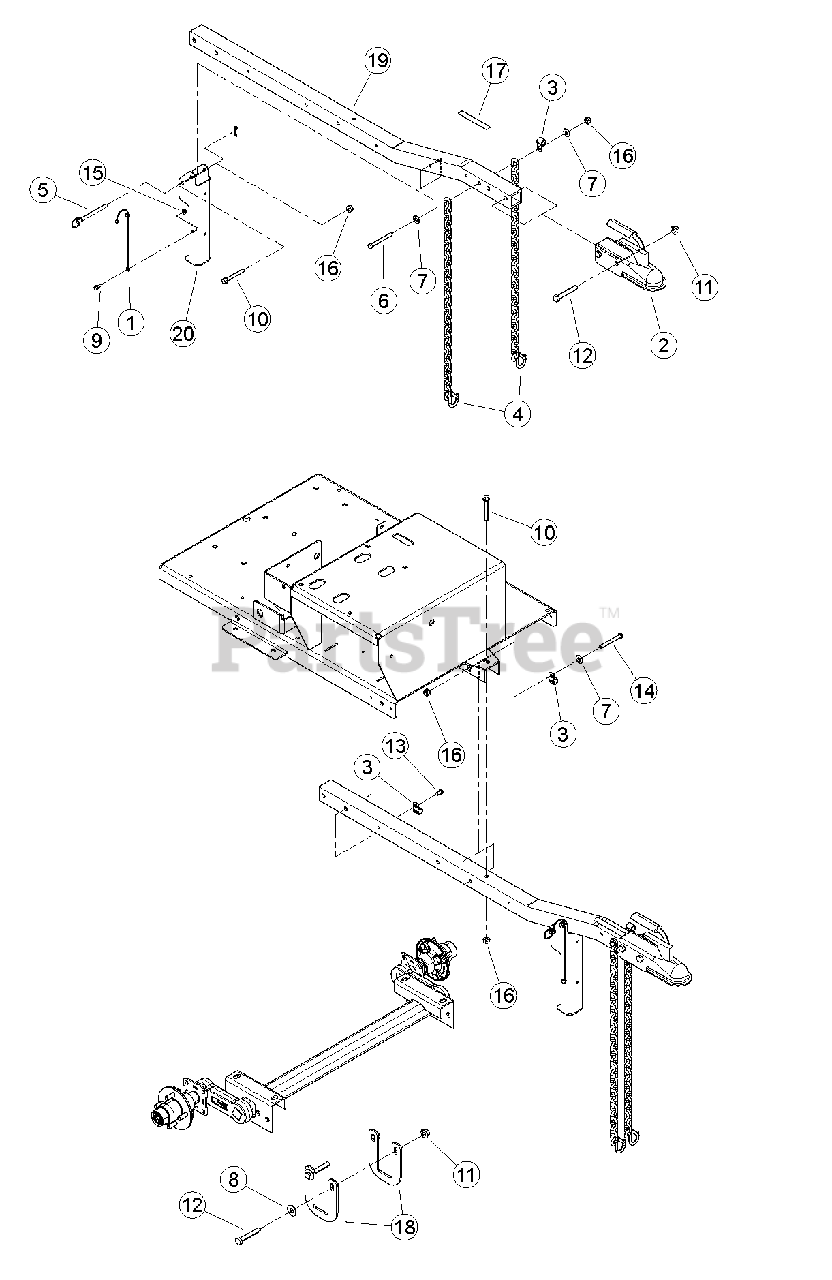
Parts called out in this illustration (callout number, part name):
1	LANYARD, NYLON
2	COUPLER, 50 MM BALL
3	CLAMP, 9/16 COATED
4	CHAIN, SAFETY 5000 LB W/ LATCH
5	PIN, 3/8 HITCH
6	BOLT, 3/8 X 3-1/2" HEX HD GR5 ZP
7	WASHER, 3/8" FLAT ZP
8	WASHER, 1/2" FLAT ZP
9	BOLT, 1/4-20 X 3/4 HWH GR5 CZP
10	BOLT, 3/8 X 3 FLANGE NC
11	NUT, 1/2-13 NYLOCK FLANGE
12	BOLT, 1/2 X 3 1/4 HCS GR5 ZP
13	SCREW, 11/32 X 7/8 HWH AB THREAD ZP
14	BOLT, 3/8 X 3-1/4 HEX HD GR5 ZP
15	NUT, 1/4-20 NYLOCK-FLANGE
16	NUT, 3/8-16 NYLOCK-FLANGE
17	DECAL, HITCH LOAD
18	PLATE, HITCH SADDLE
19	POLE, C/S HITCH
20	WELD, STAND JACK
